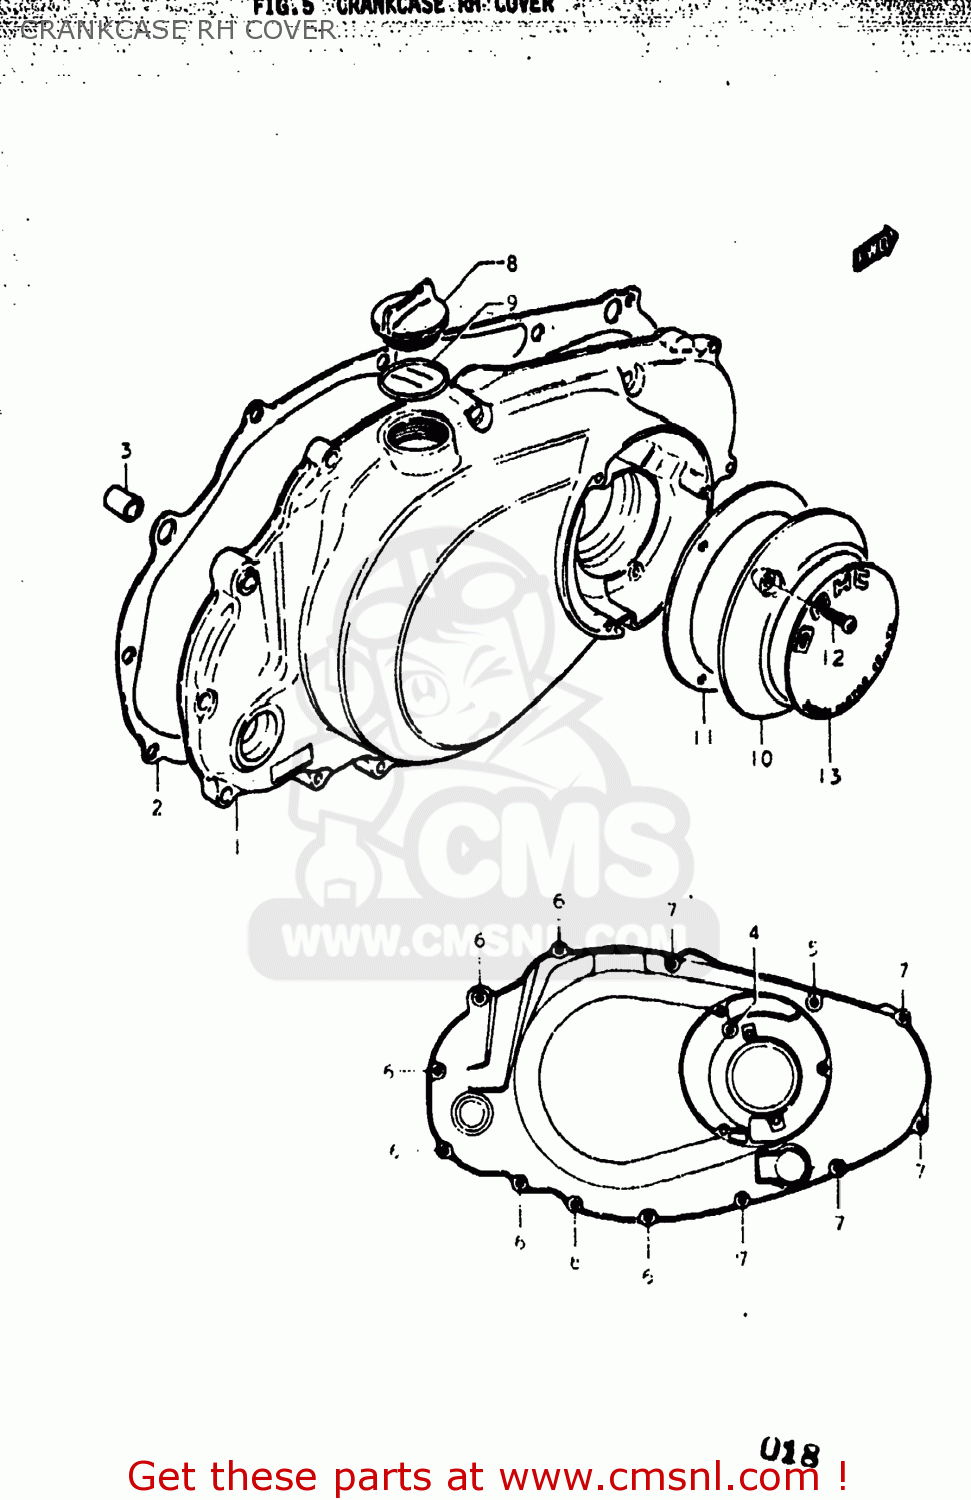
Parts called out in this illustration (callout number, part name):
1	COVER,CLUTCH
2	GASKET,CLUTCH COVER (MCA)
3	PIN
4	SCREW 6X60
5	SCREW (6X45)
6	SCREW (6X35)
7	SCREW
8	CAP
9	O RING(D:2.2,ID:32)
10	COVER,CONTACT BREAKER
11	GASKET,CONTACT BREAKER (MCA)
12	SCREW
13	EMBLEM
